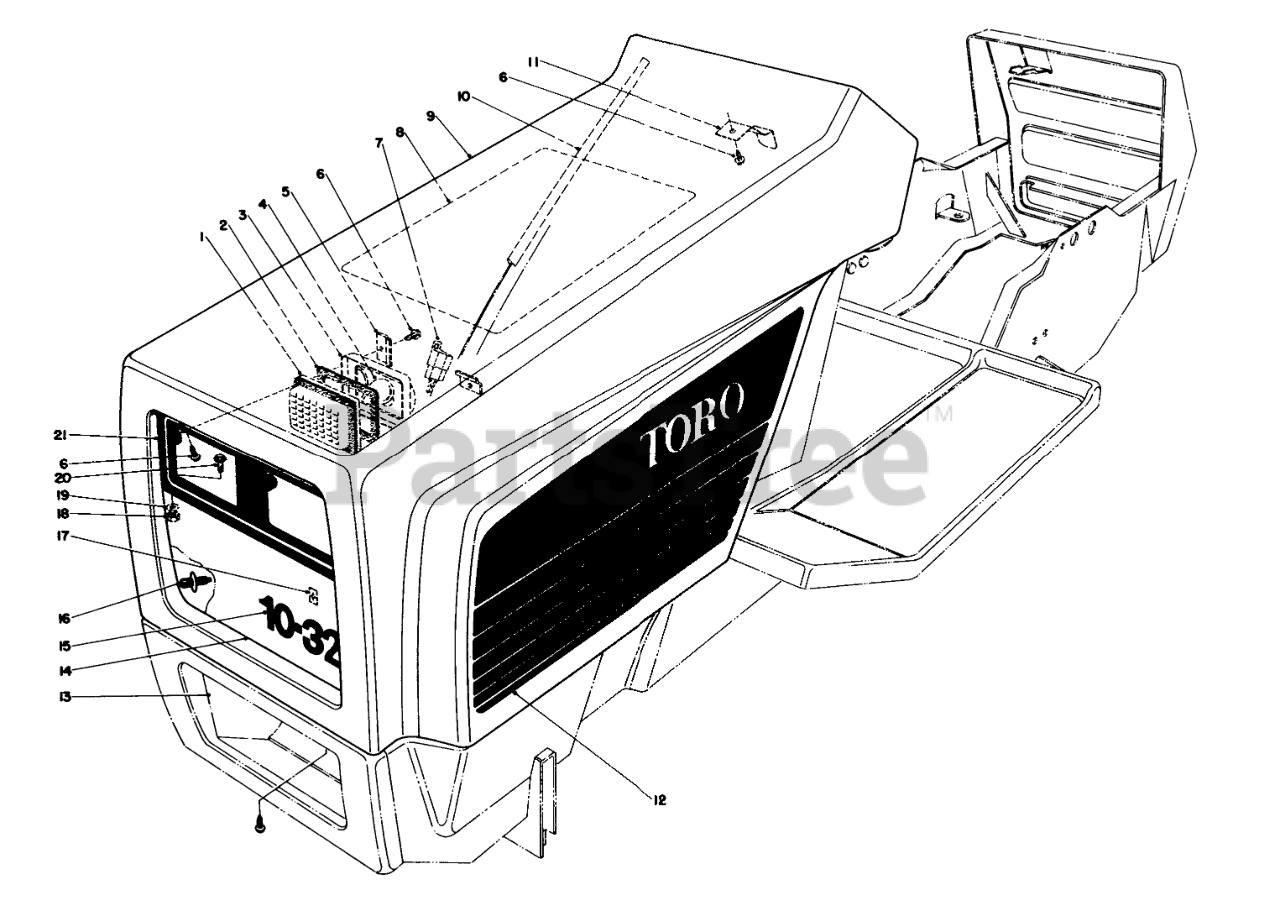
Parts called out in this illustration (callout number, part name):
1	Lens
2	Gasket Lens
3	Lamp-Green
5	HEADLIGHT CLAMP
6	SCREW-HWHTF
7	CONNECTOR BODY
8	Decal Service
10	RUBBER EXT SEAL
11	SPRING LATCH
12	Decal Hood LH.
13	LOWER GRILLE
14	Grille Headlight
15	Name Plate-Grille (Model #57351)
16	HINGE BRKT STUD
18	NUT-LOCK, SIDE
19	WASHER-FLAT
20	SCREW-SHWH
21	HEADLIGHT PANEL B
